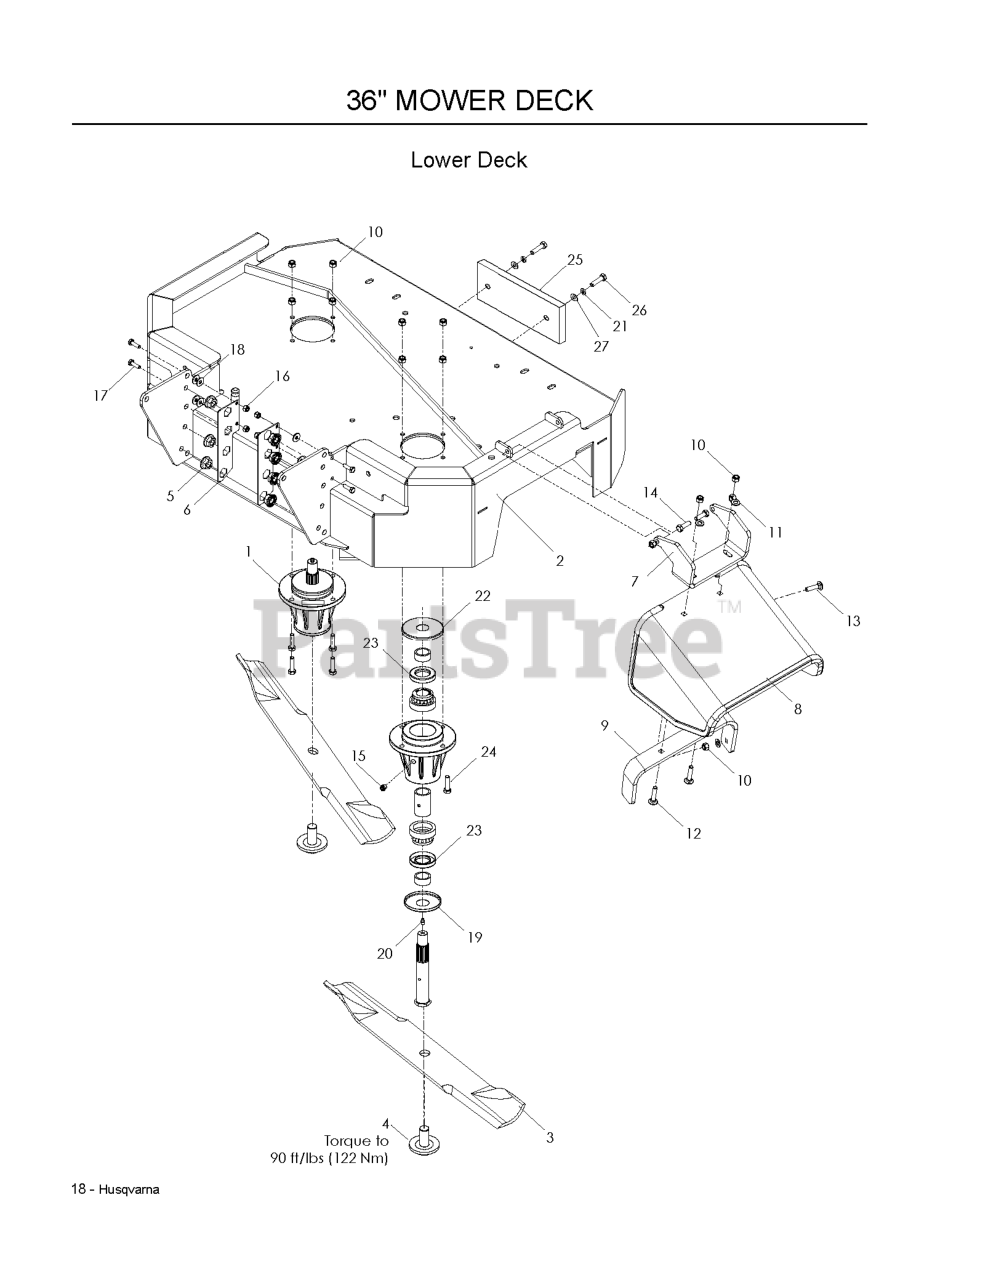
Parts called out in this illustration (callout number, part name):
1	HOUSING ASM, 72
2	DECK SVC WH3615 W/DECALS
3	BLADE OEM 18"
4	BLADE BOLT/WASHER
5	NUT FLANGE 1/2-13 GR 5
6	PLATE NUT - PAINTED
7	HINGE CHUTE - BLACK
8	CHUTE, RUBBER DISCHARGE WB
9	BRKT, REINF-CHUTE WB
10	NUT 5/16 NYLOC
11	FLAT WASHER 5/16 SAE
12	RHSNB 5/16-18 X 1-1/2 GR 5 ZD
13	BOLT, CARRIAGE 5/16X1-1/4
14	HCS 5/16C X 1
15	PLUG-VENTED
16	NUT.1/4-20.HEX.NYLOC.ZD
17	HCS 1/4-20X7/8 GR5
18	WASHER 1/4 FLAT
19	BOTTOM DUST CAP
21	WASHER 1/2" SPLIT LOCK
22	TOP DUST CAP
23	SHAFT SEAL
24	HCS 5/16C X 1 1/4
25	WEIGHT, COUNTER, ORANGE
26	HCS 1/2-13 X 1-1/2 GR 5 ZD
27	WASHER 1/2" FLAT
